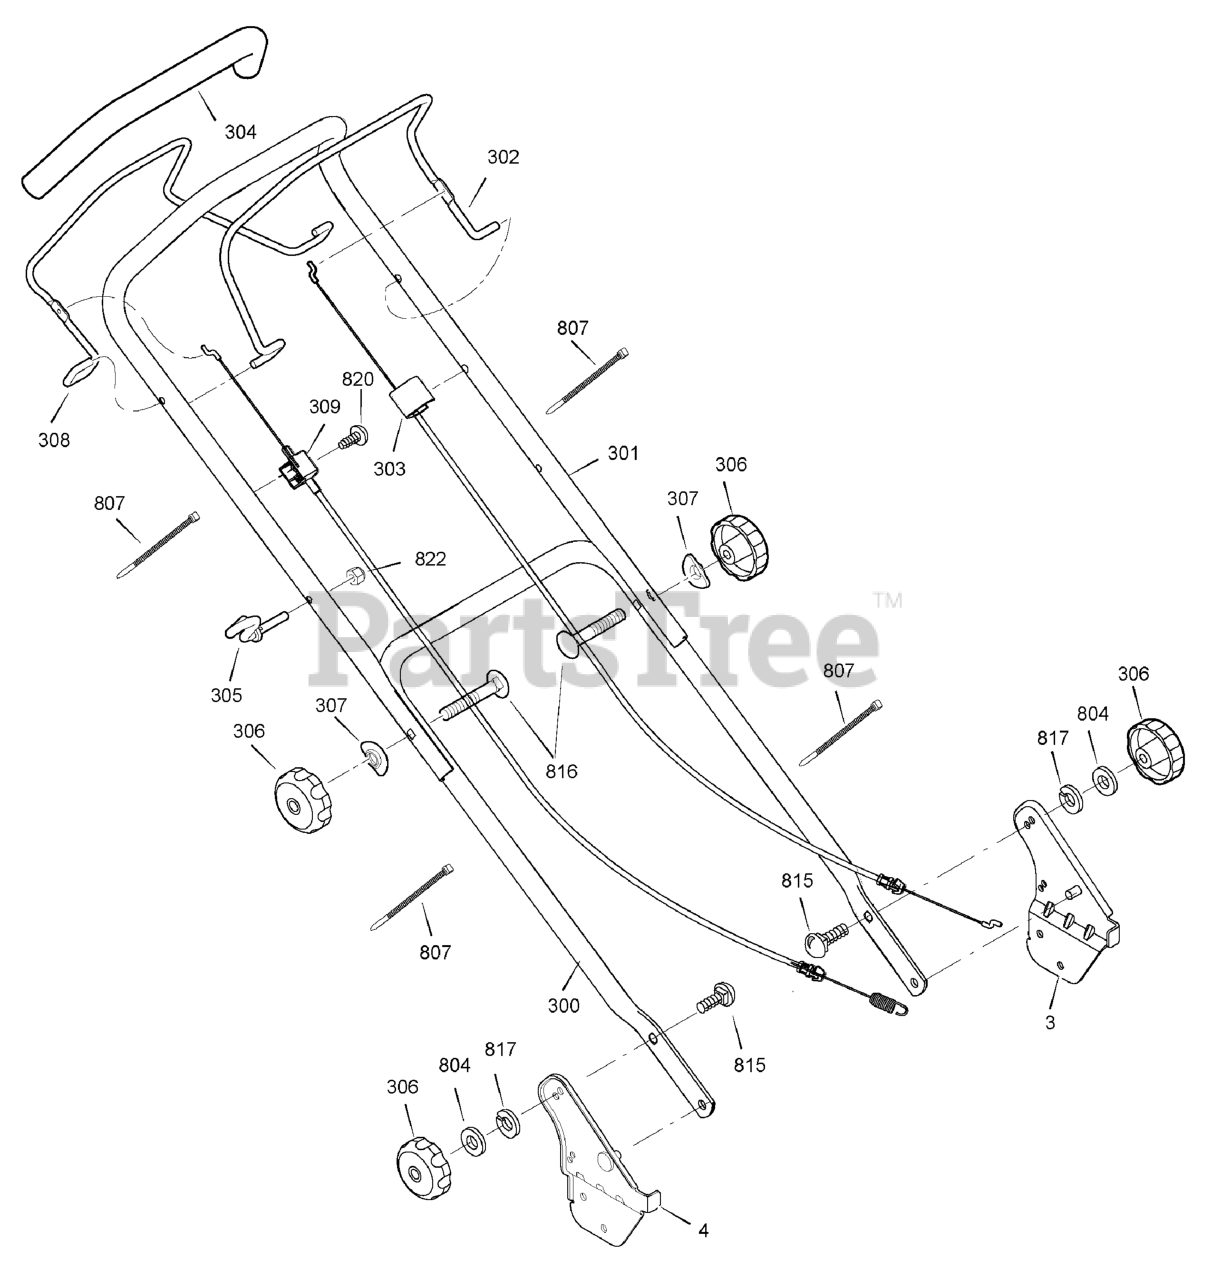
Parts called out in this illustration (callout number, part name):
300	HANDLE, Lower
301	HANDLE, Upper
302	LEVER, Engine Stop
303	CABLE, Engine Stop
304	TUBING, Foam
305	GUIDE, Rope
306	KNOB, 5/16-18
307	WASHER, Formed
308	LEVER, Drive
309	CABLE ASSEMBLY, Drive
804	WASHER, 5/8
807	CABLE TIE
815	BOLT, Carriage, 5/16-18 x 1-1/8
816	BOLT, Carriage, 5/16-18 x 2
817	Washer, Lock
820	SCREW, Tap, #10 x 1-1/4
822	NUT, Hex, 1/4-20
